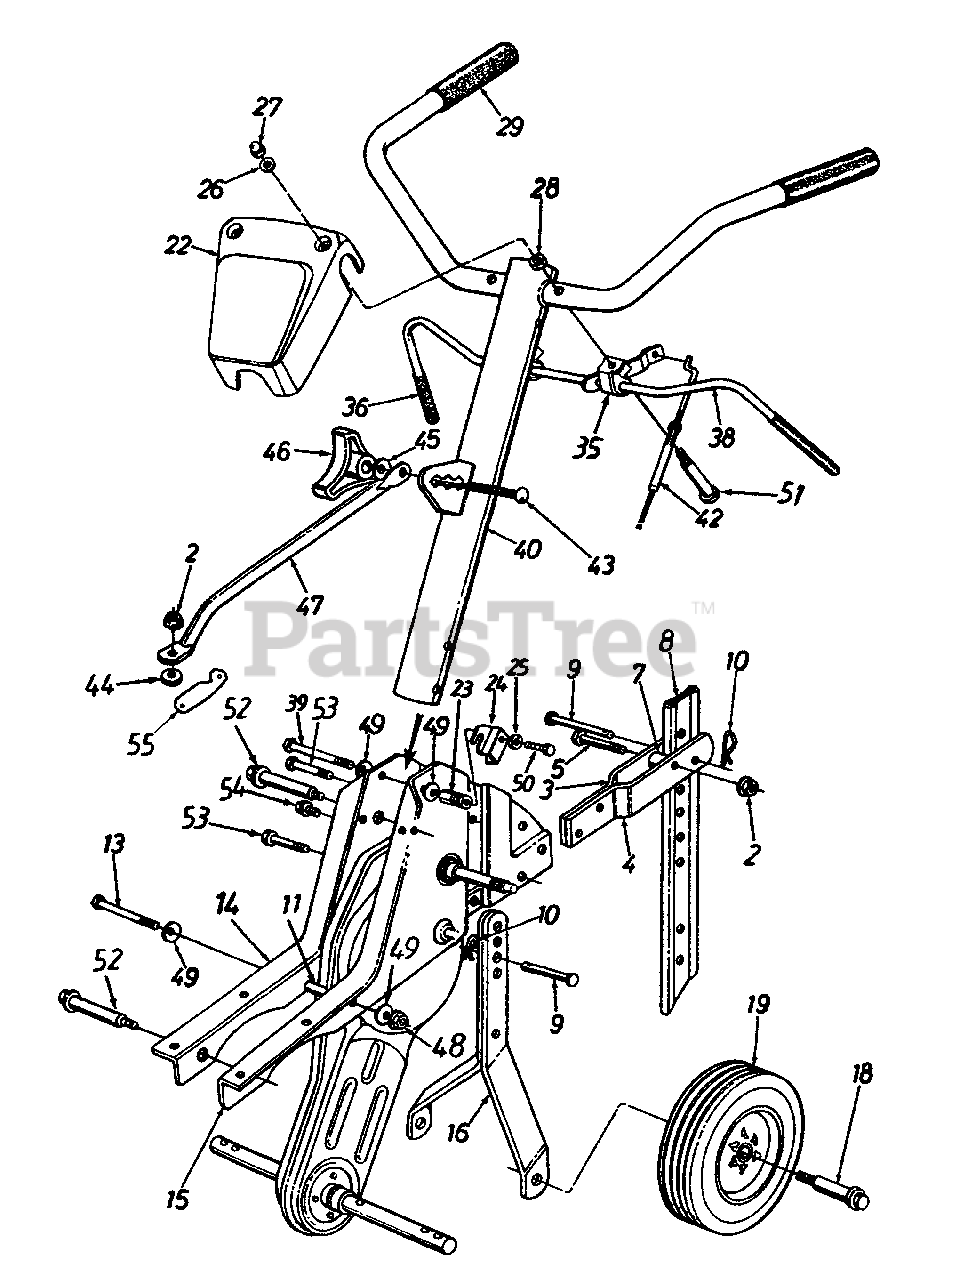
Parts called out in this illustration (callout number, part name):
2	Hex Flange L-Nut 5/16-18 Thd. (Gr. 5)
5	Hex Bolt 5/16-18 x 1.5" Lg.
7	Spacer .32" I.D. x .75" O.D.
9	Clevis Pin .375" I.D. x 1.62" Lg.
10	Intemal Cotter Pin
11	Spacer .326" I.D. x .47" O.D.
13	Hex Bolt 5/16-18 x 2.75" Lg.
18	Shld. Bolt .498" Dia. x 1.45" Lg.
19	Wheel Ass'y.
22	Handle Cover
23	Spec. Hex Nut
25	L-Wash. 5/16" I.D.
26	Fl-Wash. .266" I.D. x .625" O.D.
27	Hex L-Stop Nut 1/4-20 Thd.
28	Hex Nut 1/4-20 Thd.
29	Grip - Handle
35	Clutch Handle Holder
36	Grip - Clutch
39	Hex Bolt 5/16-18 x 3" Lg.
43	Carr. Bolt 5/16-18 x 1" Lg
46	Hand Knob
49	Bell-Wash. .345" I.D. x .88" O.D.
50	Hex Bolt 5/16-18 x .75" Lg. (Gr. 5)
51	Hex Bolt 1/4-20 x 2.25" Lg.
52	Shld. Bolt
53	Hex Wash. Hd. TT-Tap Scr. 5/16-18 x .62" Lg.
54	Hex Wash. Hd. TT-Tap Scr. 5/16-18 x 1" Lg.
55	Engine Brkt.
